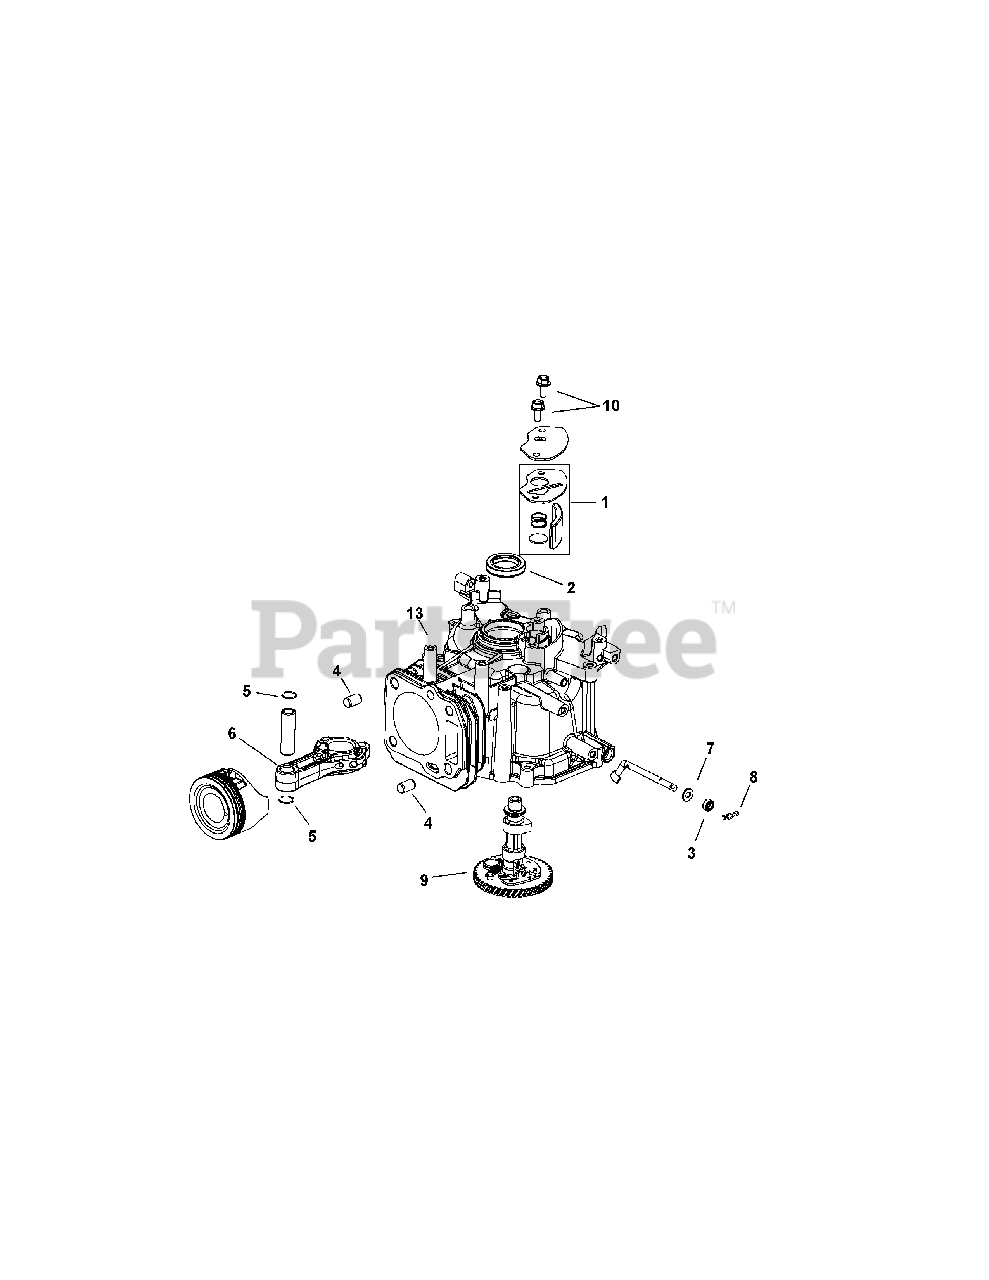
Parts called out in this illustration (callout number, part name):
1	Breather Filter Kit
4	Cylinder Head Dowel
5	Piston Pin Retainer
6	Connecting Rod
7	Flat Washer (Dia. 13mm O.D.)
8	Governor Shaft Clip
9	Camshaft Assembly
10	Hex Flange Screw, M6
